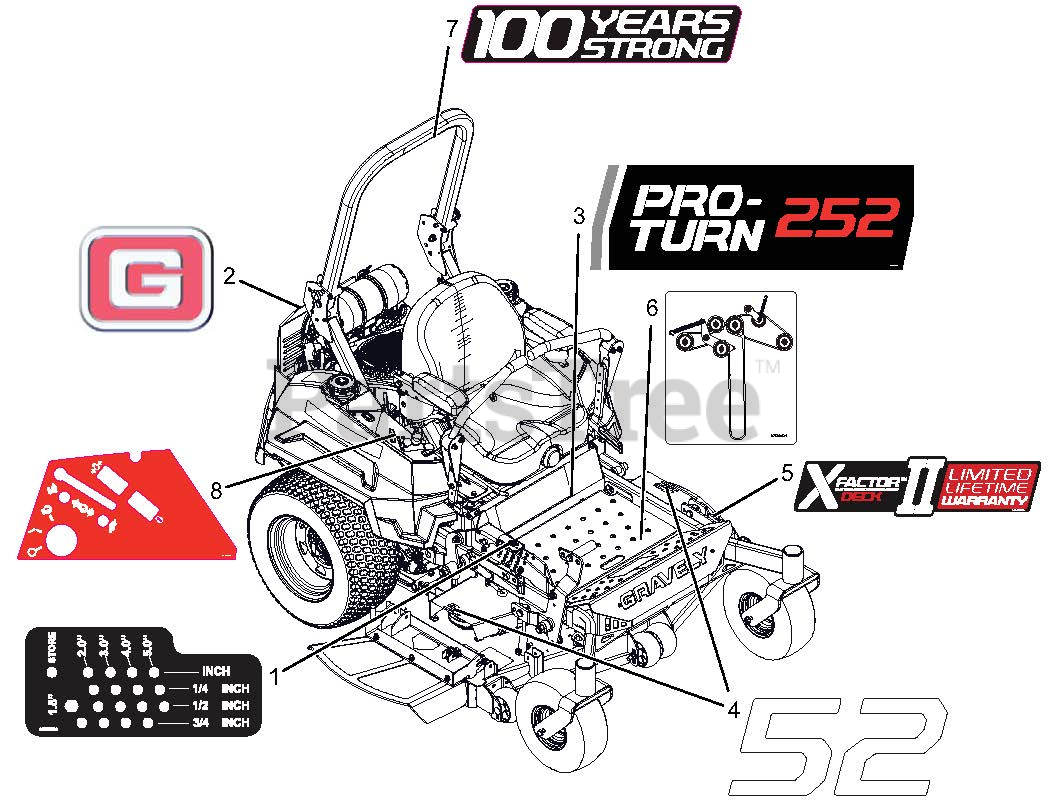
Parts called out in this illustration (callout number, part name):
1	DECAL, HEIGHT OF CUT
2	DECAL, GRAVELY BRAND
3	DECAL, PRO-TURN 252
4	DECAL, 52"
5	DECAL, X-FACTOR DECK
6	DECAL, BELT ROUTE RH V-SIDE IDLER
7	DECAL, GRAVELY 100 YEAR
8	DECAL, EFI CONTROL PANEL
